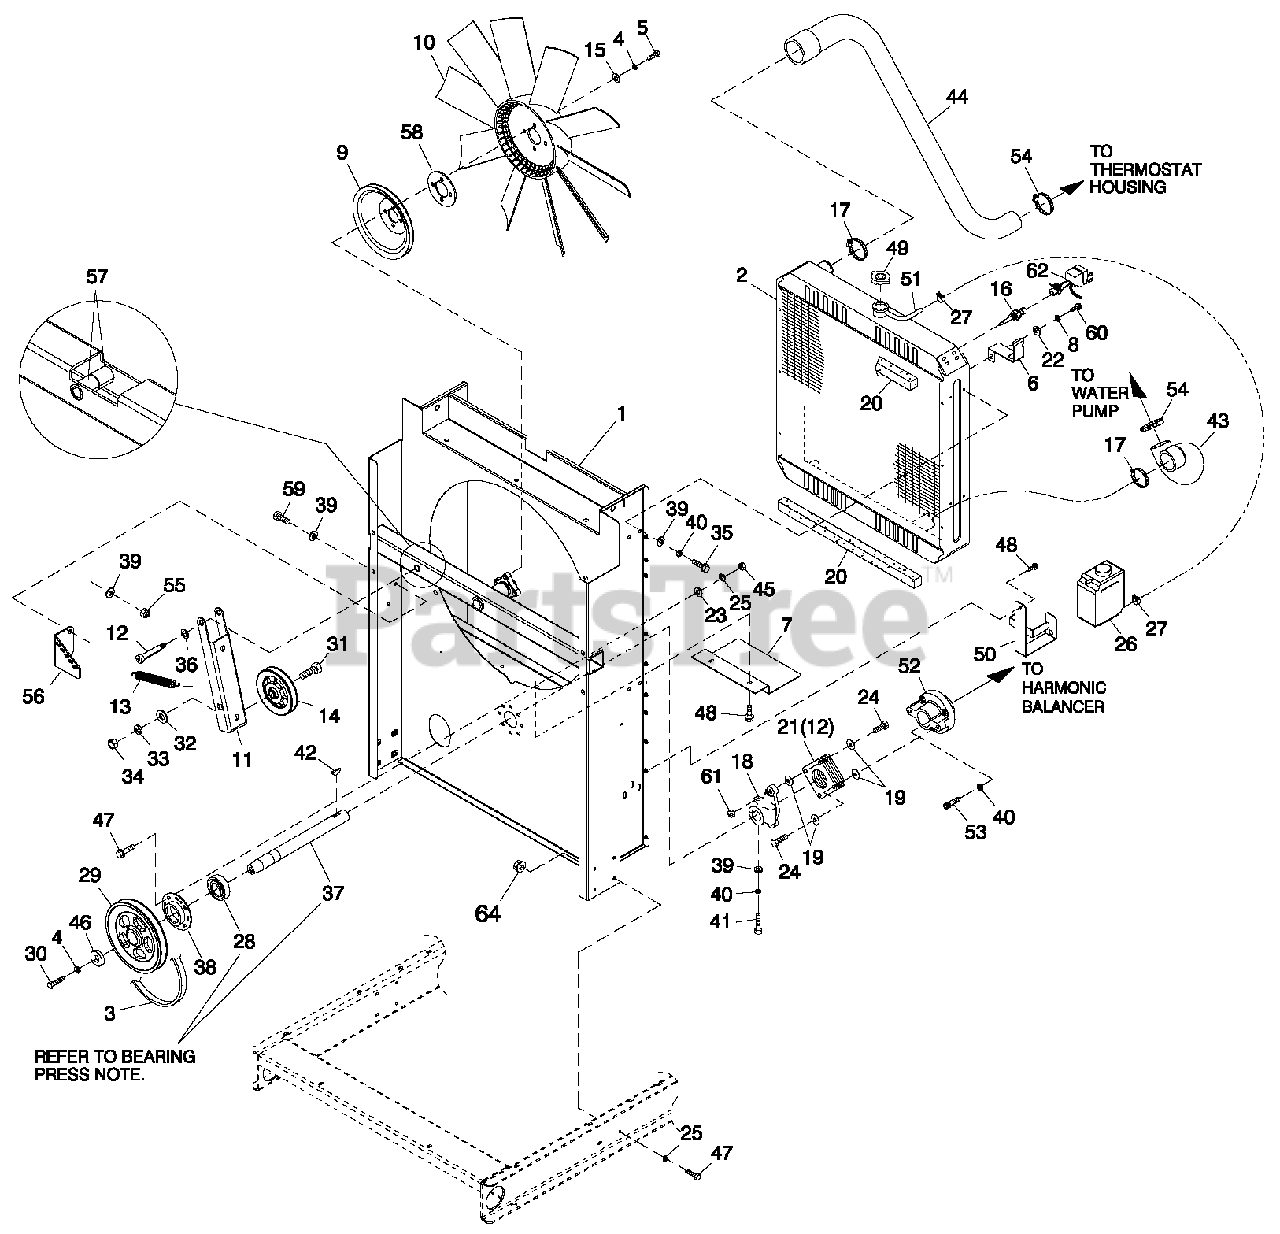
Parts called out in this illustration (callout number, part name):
1	WELDMENT RADIATOR SUPPORT C2
2	RADIATOR 598 X 568 X 49,CPL LH
3	V-BELT A58 (60IN O.C.) DDC S60
4	WASHER LOCK M10
5	SCREW HHC M10-1.5X 30 G10.9
6	BRACKET, SIGNAL CONDITIONER (USED ONLY WITH QTA PRODUCT)
7	SHIELD RADIATOR C4
8	WASHER LOCK M8-5/16 (USED ONLY WITH QTA PRODUCT
9	PULLEY FAN V-GROOVE 9"
10	FAN COOL 22" D IA 10 BLADE LH
11	ARM BELTTENSIONER
12	SHOULDER BOLT 1/2 X 2-1/4"
13	SPRING TENSION CPL
14	PULLEY V- BELT 4" FLANGED
15	WASHERFLAT 3/8-M10ZINC
16	PRO BE COOLANT LEVEL 3/8 NPTF
17	CLAMP HOSE #28 1.32-2.25
18	HU B FLEX PLATE
19	WASHER FLEX (THIN)
20	TAPE FOAM 1 X 1 (26.75" LG)
21	DISK FLEX
22	WASHER FLAT 5/16-M8 ZINC (USED ONLY WITH QTA PRODUCT)
23	WASHERFLAT 1/4-M6 ZINC
24	SCREW HHC 5/16-24X1.124
25	WASHER LOCK M6-1/4
26	TANK COOLANT RECOVERY
27	CLAMP HOSE BAND 1/4
28	BEARING #6205 2NSE C3 E SRI2 S
29	PULLEY 6.5" DIA MACHINED
30	SCREW HHC M10-1.5X30G8.8
31	SCREW HHC 1/2-13X2" G8
32	WASHERFLAT 1/2 ZINC
33	WASHER LOCK 1/2
34	NUT HEX 1/2-13 STEEL
35	SCREW HHFC M8-1.25 X 20 W/M6
36	WASHER NYLON .50 X .87 X .06
37	SHAFT FAN DRIVE
38	RETAINER BEARING
39	WASHERFLAT 5/16-M8ZINC
40	WASHER LOCK M8-5/16
41	SCREW HHC M8-1.25X45C8.8
42	KEY WOODRUFF 4X 1 9D
43	HOSE RADIATOR LOWER FRONT
44	HOSE RADIATOR UPPER FRONT
45	NUT HEX M6X 1.0 G8 YEL CHR
46	SPACER .5 X 1.5 X .25 STL/ZINC
47	SCREW HHFC M6-1.0X 2 0 G8.8
48	SCREW THF M6-1 X 16 N WA Z/JS
49	CAP RADIATOR 13 PSI
50	BRACKET COOLANT TANK
51	HOSE 9/32 ID (60"LG)
52	COUPLING FLEX HU B MACHINED
53	SCREW SHC M8-1.25 X 30 G12.9
54	CLAMP HOSE #24 B1.06-2.00
55	NUT HEX LOCK M8-1.25 NY INS
56	BRACKET TENSIONERSPRING
57	BEARING SLEEVE 1/2/X 3/4 X 1
58	SPACER CPL COOLING FAN 1/8"
59	SCREW HHC M8-1.25X20C8.8
60	SCREW HHFC M8-1.25X20 W/M6 (USED ONLY WITH QTA PRODUCT)
61	NUT HEX LOCK 5/16-24 NY INS
62	ASSY PC B LCL SENSOR (USE WITH I/N 16, P/N 0H1827 ONLY)
64	NUT FLANGE M6-1.0 NYLOK
